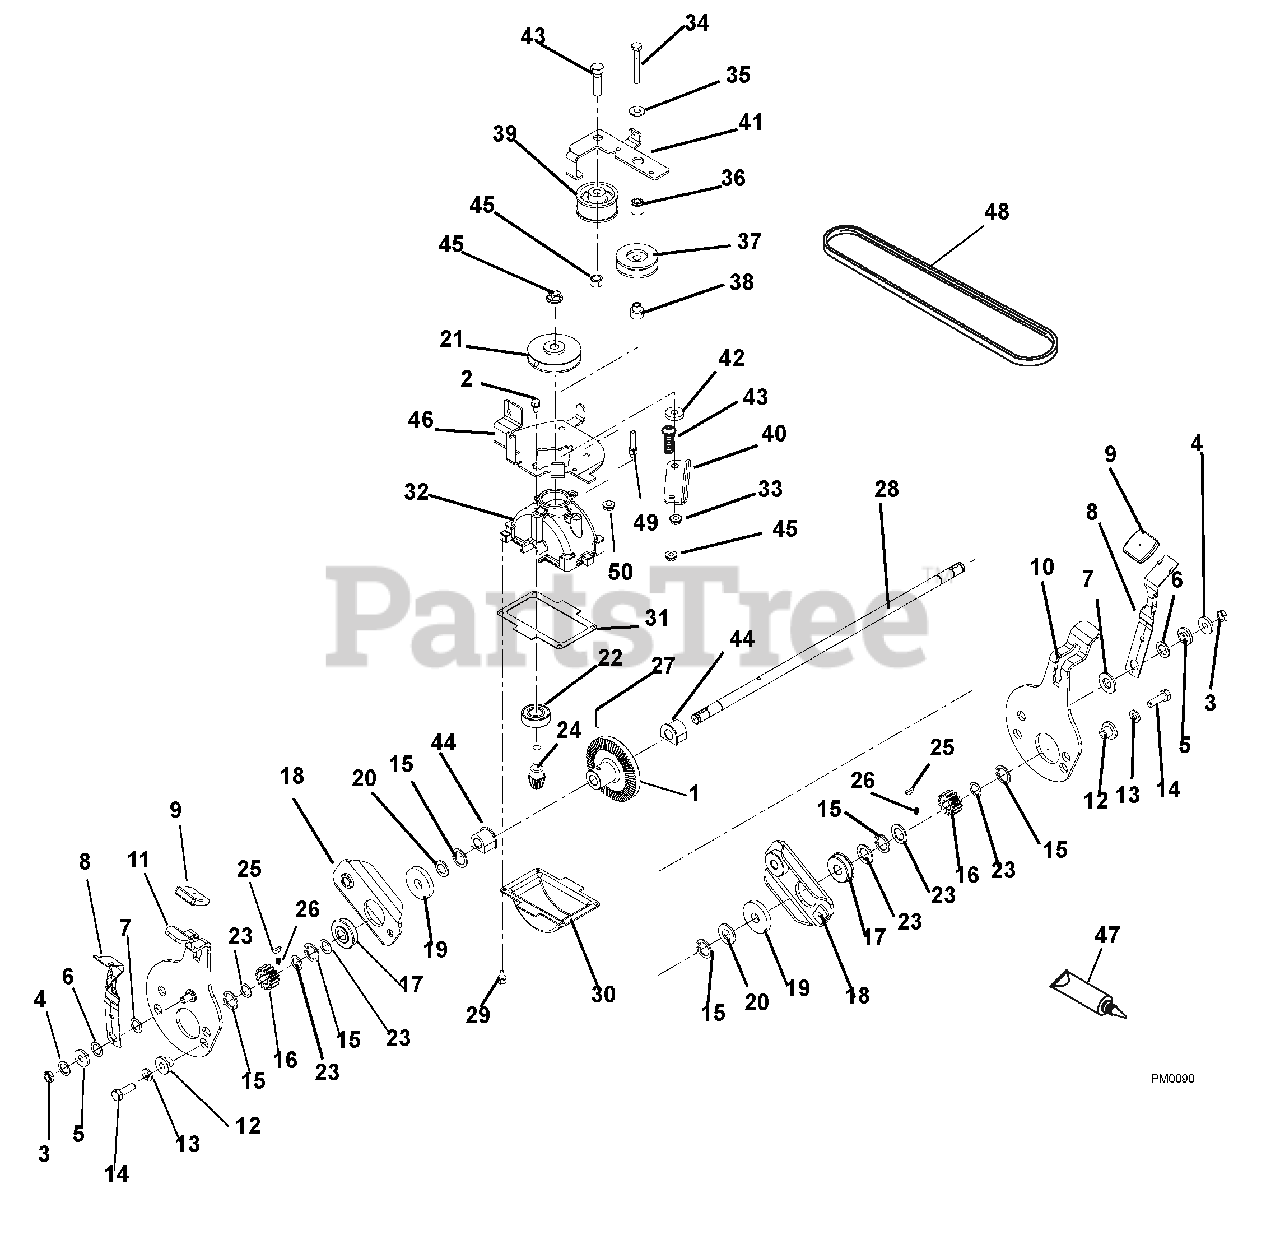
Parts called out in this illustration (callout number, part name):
1	GEAR, REDUCTION
2	@SCR-TAP 10-24X.375 HWH YZ TR
3	@NUT-LK-CTR .31-18 YWZC
4	@WSHR-FL-STL.38X.875X.083 YWZC
5	BSHG-FLG .265X.437X.250X.750
6	WSHR-FL-STL .52X.827X.062 YWZC
7	WSHR-FL-STL .630X1.005X.062 YZ
8	LEVER, HEIGHT ADJUSTMENT
10	WELDMT-DETENT SUPPORT RIGHT
11	WELDMT-DETENT SUPPORT LEFT
12	BSHG-FLG .325X.500X.513X.875
13	@WSHR-LK .31X.078 REG YWZC
14	@BLT-HEX .31-18X1.00 GR5 YWZC
15	RG-RTNG-EXT.50 X .034
16	PINION-WBLM DRIVE
17	BRG-BALL .50X1.38X.438 SEALED
18	ARM,WHEEL MOUNT
19	WSHR-FL-STL .515X1.625X.250 YZ
20	@WSHR-FL-STL.531X1.06X.095YWZC
21	PULLEY, TRANS INPUT
22	BRG-BALL .625X1.375X.43
23	WASHER, .500X.750X.020 THRUST
24	PINION, GEARBOX INPUT
25	KEY-WDRF .125X.50X.20 (HRDEND)
26	SPRING, .134X.180X.144 COMP.
28	SHAFT - TRANSMISSION OUTPUT
29	@SCR-TAP 10-24X.375 HWH YZ TR
30	SUMP, GEARBOX
31	GASKET, TRANSMISSION
32	HOUSING, WBLM GEAR BOX
33	@NUT-LK-TOP-FLG .25-20 YWZC
34	@BLT-HEX .25-20X2.00 GR5 YWZC
35	@WSHR-FL-STL.312X.734X.065 YWZ
36	SPACER, IDLER ARM
37	IDLER, 3L FRONT SIDE .38X1.875
38	SPACER, V-IDLER PULLEY
39	IDLER - FLAT 1.875OD X .75WIDE
40	STRAP,TRANSMISSION
41	ARM-TRANS IDLER
42	@WSHR-FL-STL.406X.812X.065 YWZ
43	@BLT-HEX .38-16X1.25 GR5 YWZC
44	BUSHING, TRANS OUTPUT SHAFT
45	@NUT-LK-TOP-FLG .38-16 YWZC
46	BRACKET, TRANSMISSION CONTROL
47	LUBRICATE
48	V-BELT, 3L-WRAPPED
49	FINGER, BELT
50	@NUT-SPNLK-FLG .25-20 YWZC
